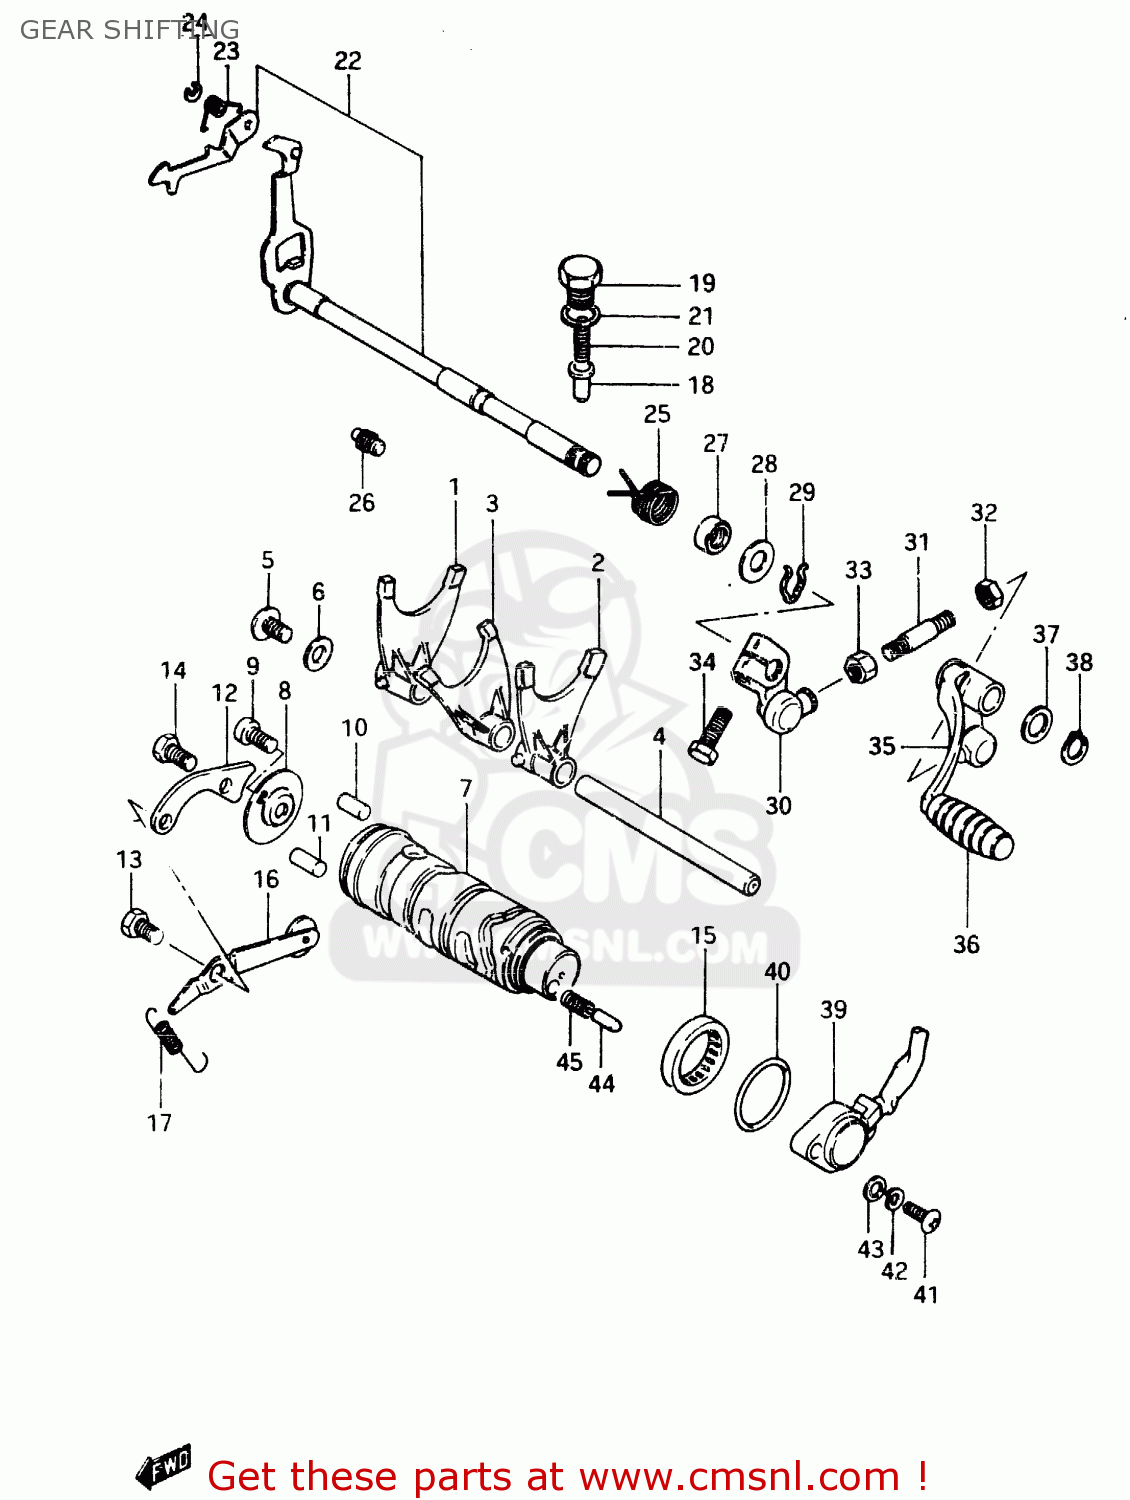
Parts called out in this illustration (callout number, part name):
1	FORK, GEAR SHIFTING
2	FORK, GEAR SHIFTING
3	FORK, GEAR SHIFTING
4	SHAFT,GEAR SHIFT FORK
5	SCREW
6	WASHER
7	CAM,GEAR SHIFT
8	RETAINER,GEAR SHIFT CAM DR PIN
9	SCREW
10	PIN
11	PIN(4X18.5)
12	GUIDE,GEAR SHIFT CAM
13	BOLT
14	BOLT, UPPER
15	BEARING(40X47X12)
16	STOPPER,GEAR SHIFT CAM NO.1
17	SPRING
18	STOPPER,GEAR SHIFT CAM NO.2
19	HOLDER,GEAR SHIFT CAM STOP SPR
20	SPRING
21	GASKET(14X19.2X2) (NAS)
22	SHAFT, GEAR SHIFTING
23	SPRING
24	E RING
25	SPRING
26	STOPPER,GEAR SHIFT CAM
27	OIL SEAL
28	WASHER (12.5X27X1.6)
29	SPRING,RETAINER
30	ARM,GEAR SHIFT LINK
31	ROD,GEAR SHIFT LINK
32	NUT
33	NUT
34	BOLT
35	LEVER ASSY,GEAR SHIFT
36	RUBBER,GEAR SHIFT PEDAL
37	WASHER(12.5X20X1)
38	CIRCLIP
39	BASE ASSEMBLY,NEUTRAL SWITCH TERMINAL
40	O-RING (D:2.4 ID:26.2)
41	SCREW 5X20
42	LOCK WASHER
43	WASHER
44	PIN(5X15.5)
45	SPRING
